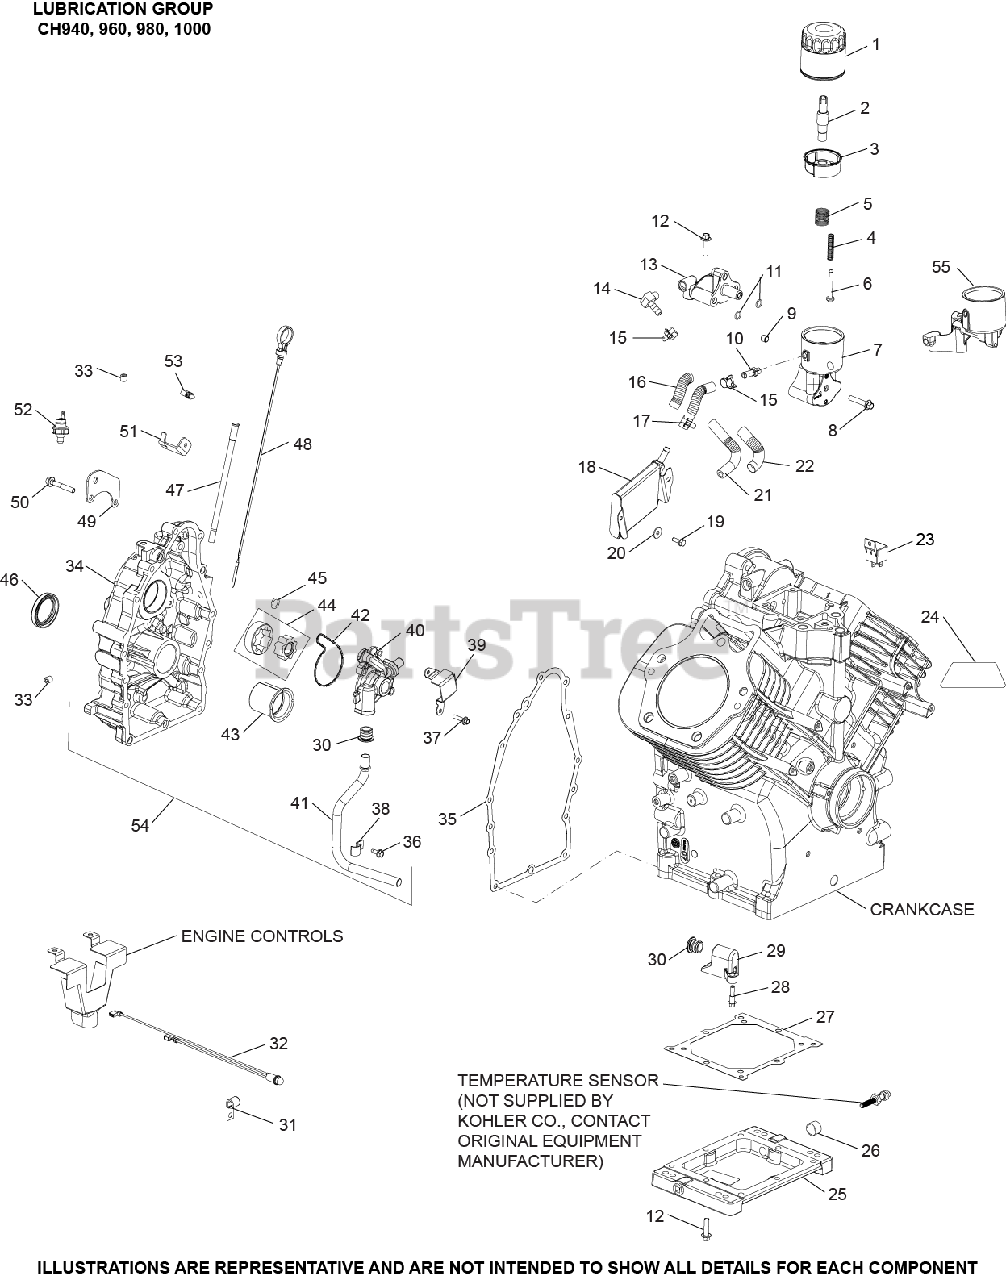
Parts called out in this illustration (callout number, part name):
1	OIL FILTER
2	NIPPLE, OIL FILTER ASSEMBLY
3	CUP, OIL FILTER ASSEMBLY
4	SPRING, OIL FILTER VALVE
5	SPRING, OIL FILTER CUP
6	VALVE, OIL FILTER
10	FITTING, BARBED
11	O-RING, OIL PICK-UP
12	SCREW, FLG M8X1.25X30
16	SLEEVE, ANTI ABRASION-USE 25 431 12-S
17	HOSE, OIL RETURN
18	COOLER, OIL ASSEMBLY
19	SCREW, TAP M6X1.7X18
20	WASHER, FLAT 1/4"
21	HOSE, OIL SUPPLY
22	SLEEVE, ANTI ABRASION-USE 25 431 12-S
25	KIT, OIL RESERVOIR
27	GASKET, OIL RESERVOIR
28	SCREW, SHD THD FRM M6X.0X6.5
30	SEAL, PICK-UP TUBE
31	CLIP, CABLE
32	LIGHT, INDICATOR ASSEMBLY
33	PLUG, PIPE 1/2 NPTF SQ CTSK
33	PLUG, CTSK PIPE 1/8"
34	KIT, CLOSURE PLATE
35	GASKET, OIL PAN
36	SCREW, THREAD FORMING
41	TUBE, OIL PICK-UP
42	O-RING, OIL PUMP HOUSING
44	PUMP ASSEMBLY, OIL/GEROTOR
46	SEAL, OIL
49	STRAP, LIFTING
52	SENSOR, OIL PSI
55	KIT, OIL FILTER HOUSING
6208137-S	HOUSING, OIL PUMP MACHINED
